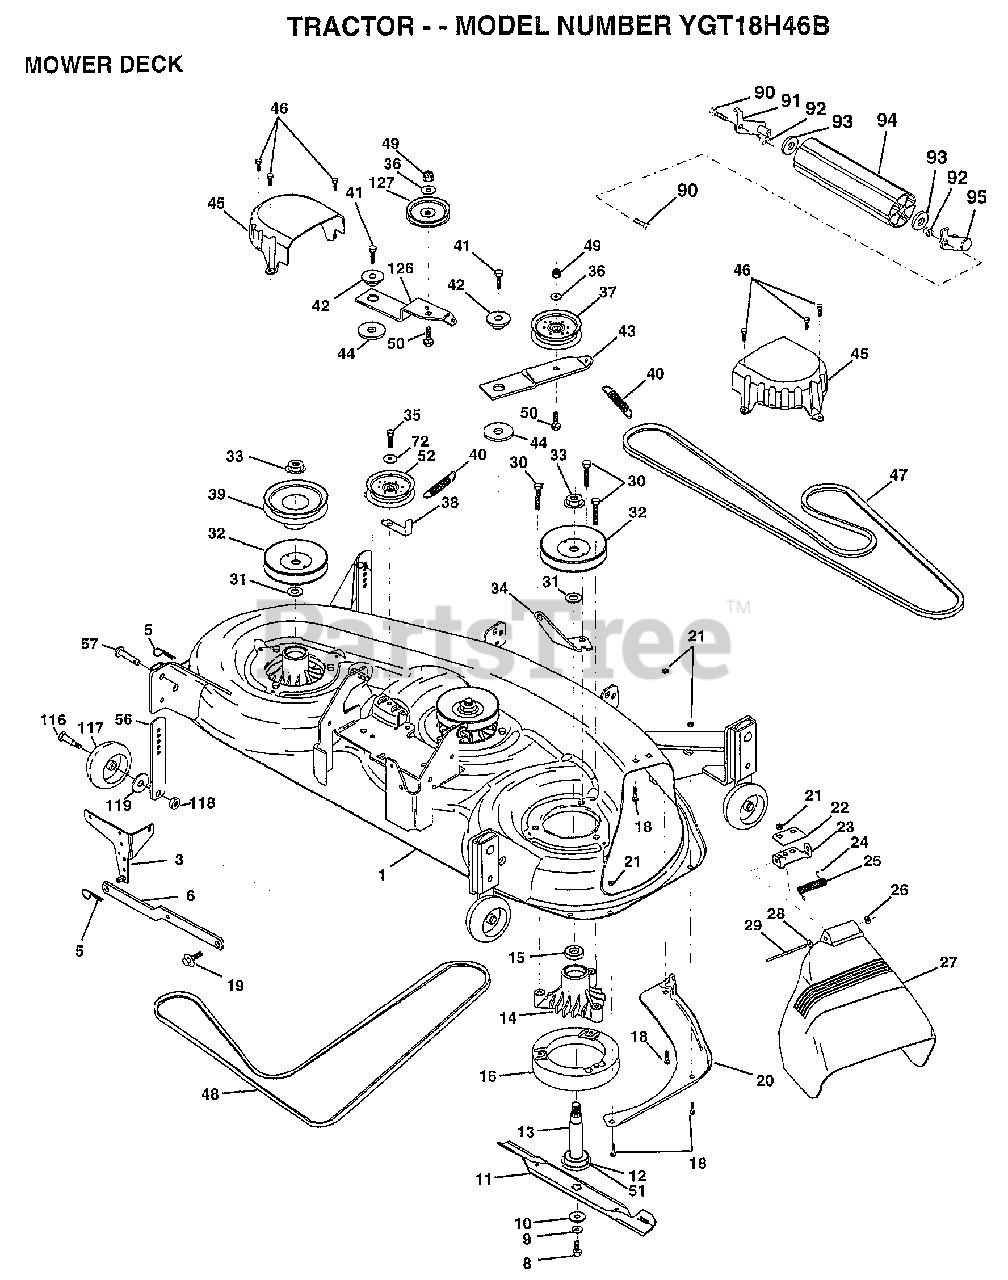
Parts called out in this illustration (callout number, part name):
1	"DECK.ASM.MOWER46"""
3	BRKT.ASM.SW.44/50
8	BLADE BOLT
10	WASHER.HARD.BLADE
11	"BLADE.HIGHLIFT46"""
12	BEARING.BALL
13	SHAFT.ASM.W/BRNG
14	HOUSING.MAND.44.V
15	BEARING
16	STRIPPER RND MWR
18	BOLT
19	BOLT SHD 5/16-18
20	BAFFFLE.VORTEX.46
22	STIFFENER BRKT
23	DEFLECTOR BRKT
27	SHIELD DEFLECTOR
28	WASHER
29	HINGE ROD
30	"SCREW-THD ROLL,WA"
31	WASHER
32	PULLEY.MAND.36/46
34	ANCHOR.SPRING.46
35	SCREW LT
36	WASHER
37	FLAT IDLER PULLEY
38	"KEEPER BELT,IDLER"
39	PULLEY.DRV.DCK.46
40	"SPRING.SEC.44""VEN"
41	SCREW
42	SPACER RETAINER
43	ARM.IDLER.DECK.46
44	HARDENED WASHER
45	COVER.MANDREL.46
46	SCREW.1/4-20X5/8
47	BELT-V.SEC.46.KEL
48	BELT V PRIM 50
50	BOLT.3/8-16X1.50
51	WASHER.FELT.
52	"PULLEY IDLER,FLAT"
72	WASHER HYT
90	BOLT
92	NUT
93	WASHER
116	BOLT.SHOULDER
117	WHEEL GAGE DONUT
118	LOCKNUT
119	WASHER
126	ARM.IDLER.PRIM.46
127	PULLEY.IDLER.4.25
